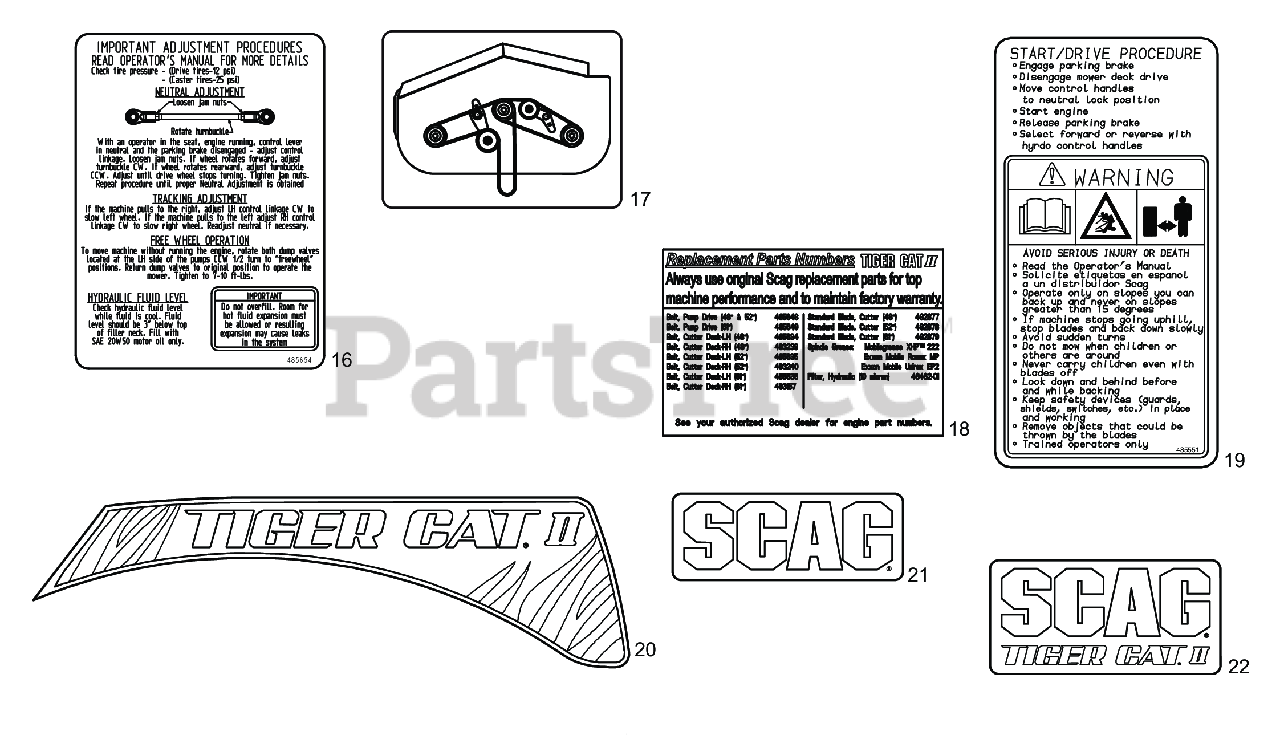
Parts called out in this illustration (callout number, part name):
16	Decal, Seat Support
17	Decal, Cutter Deck Belt Routing
17	Decal, Belt Routing (61V)
18	Decal, STCII Replacement Parts
19	Decal, Start/Drive
20	Decal, Tiger Cat II - LH
20	Decal, Tiger Cat II - RH
21	Decal, Scag
22	Decal, Scag Tiger Cat II
